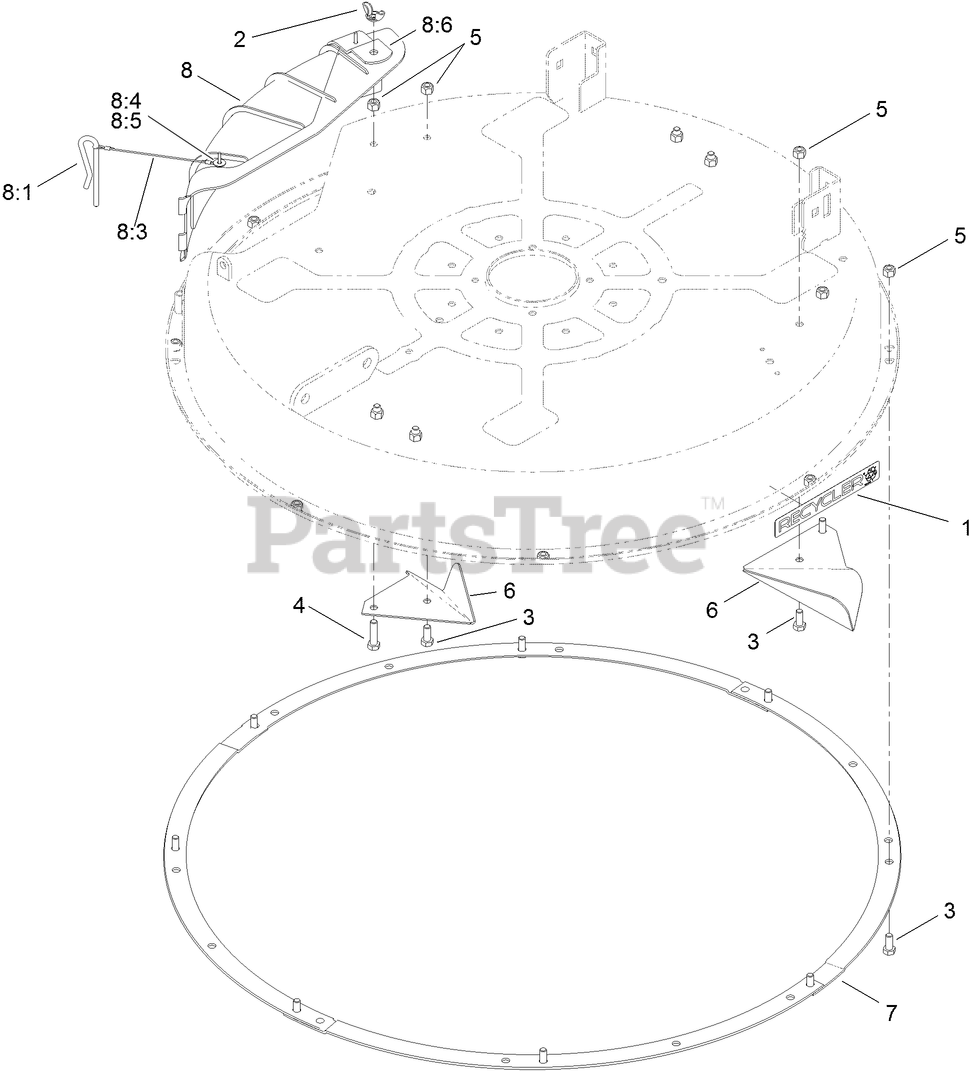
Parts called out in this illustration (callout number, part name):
1	DECAL-RECYCLER
2	NUT-WING
3	SCREW-HH
4	SCREW-HH
5	NUT-LOCK, NI
7	RING-DECK
8	DISCHARGE COVER ASM
8:1	PIN-LOCKING, CHUTE
8:3	LANYARD
8:4	RIVET-BLIND
8:5	WASHER-PLAIN
